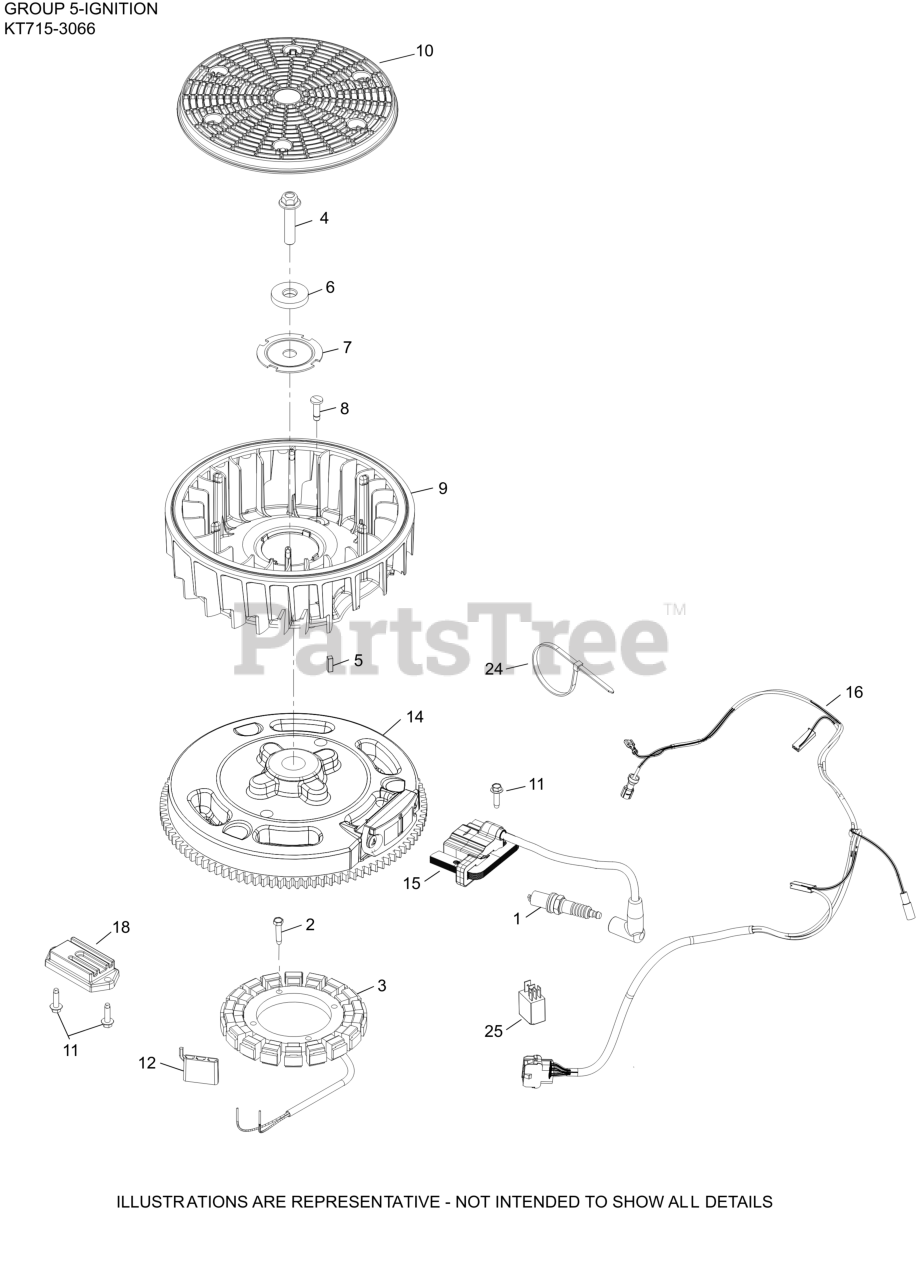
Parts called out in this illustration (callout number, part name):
1	SPARK PLUG, RFI
2	SCREW, THREAD FORMING
3	KIT, 15 / 20 AMP STATOR
4	SCREW, HEX FLANGE
5	KEY, SQUARE
6	WASHER, FLAT
7	PLATE, FAN MOUNTING
8	RETAINER, FLYWHEEL FAN
10	SCREEN, GRASS
11	SCREW, THD FRM-USE 25 086 473-S
12	CONNECTOR
14	FLYWHEEL ASSEMBLY
15	MODULE, CDI IGNITION
16	HARNESS, WIRING ASSEM.W/FUEL SHUT DOWN
18	REG/RECT12/15A HALF-WAVE STD-(#2540347S)
